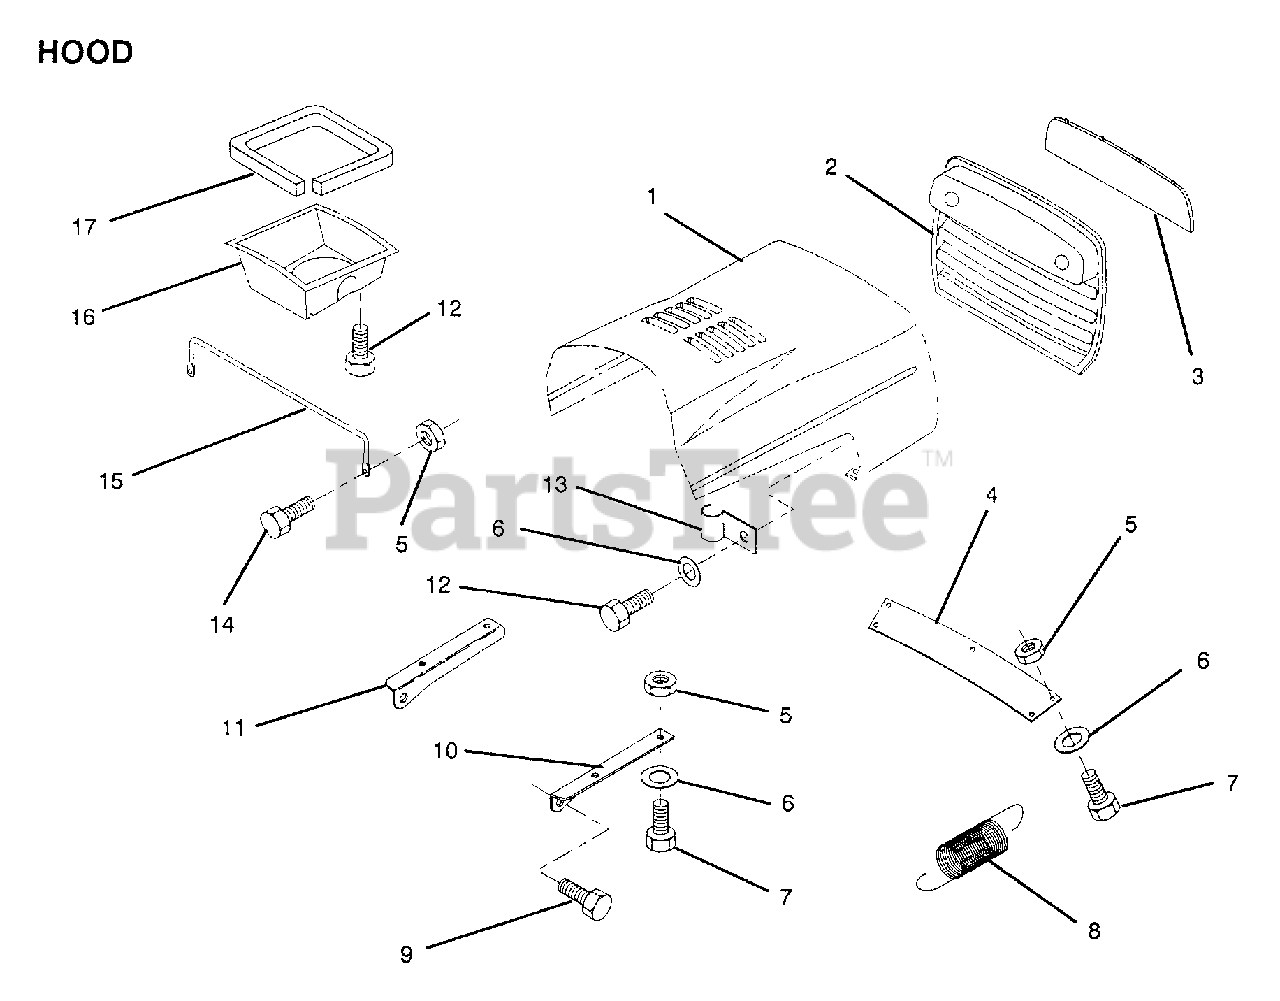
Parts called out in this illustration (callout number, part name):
5	NUT
6	WASHER
7	BOLT
8	EXT SPRING
10	BRKT HOOD RH
11	BRKT HOOD LH
13	CLIP T
15	"BRACE,HOOD"
16	"DUCT,AIR"
17	FOAM STRIP LT
